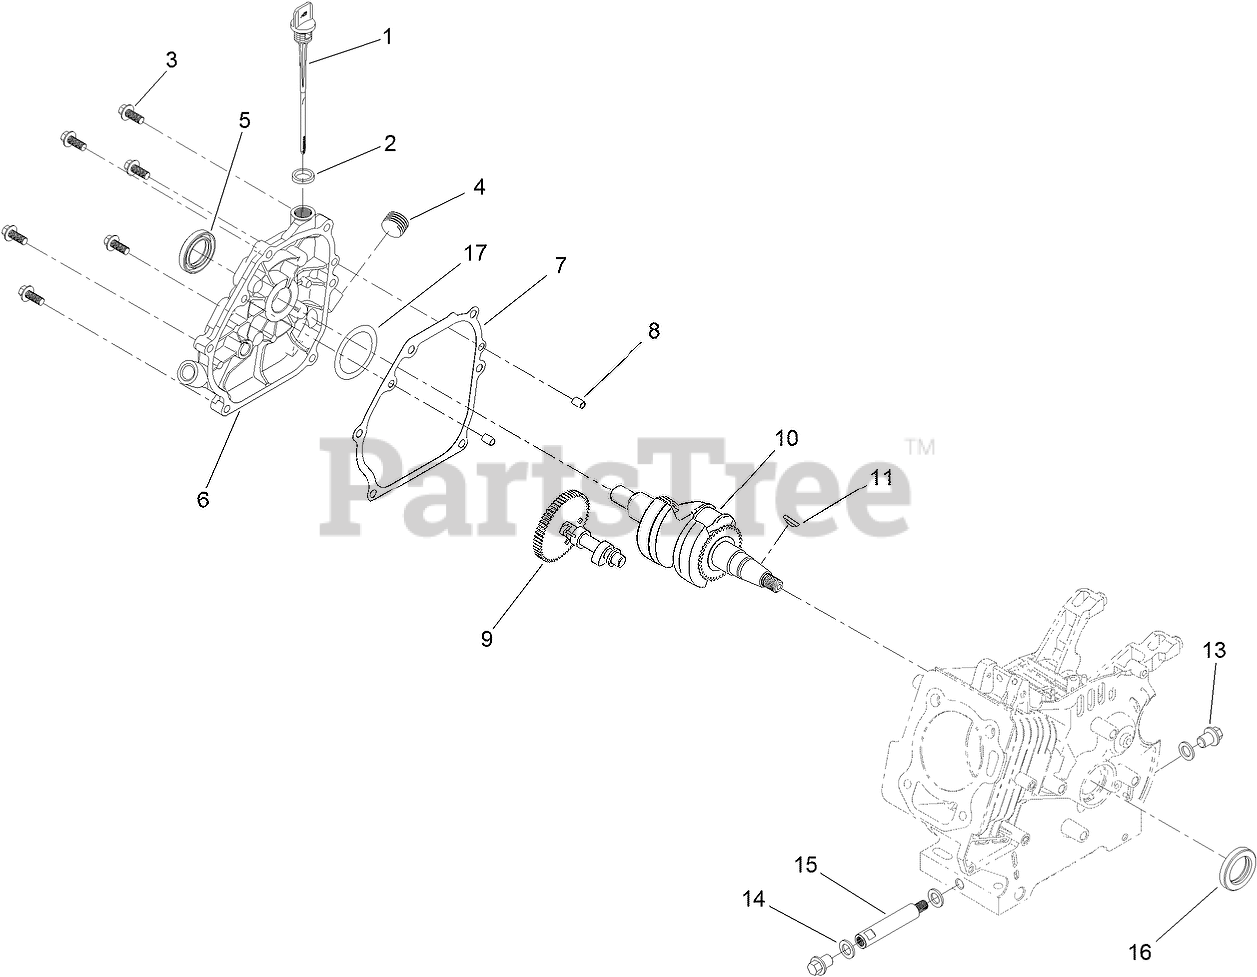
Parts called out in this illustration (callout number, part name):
1	DIPSTICK-OIL
2	GASKET-DIPSTICK, RUBBER
3	SCREW-HHF
4	PLUG-DRAIN
5	SEAL-OIL
6	COVER-CRANKCASE
7	GASKET-COVER, CRANKCASE
8	PIN-DOWEL
9	CAMSHAFT ASM
10	CRANKSHAFT
11	KEY-WOODRUFF
13	SCREW-HHF
14	WASHER-PLAIN
15	TUBE-DRAIN, OIL
16	SEAL-OIL
17	WASHER-THRUST
